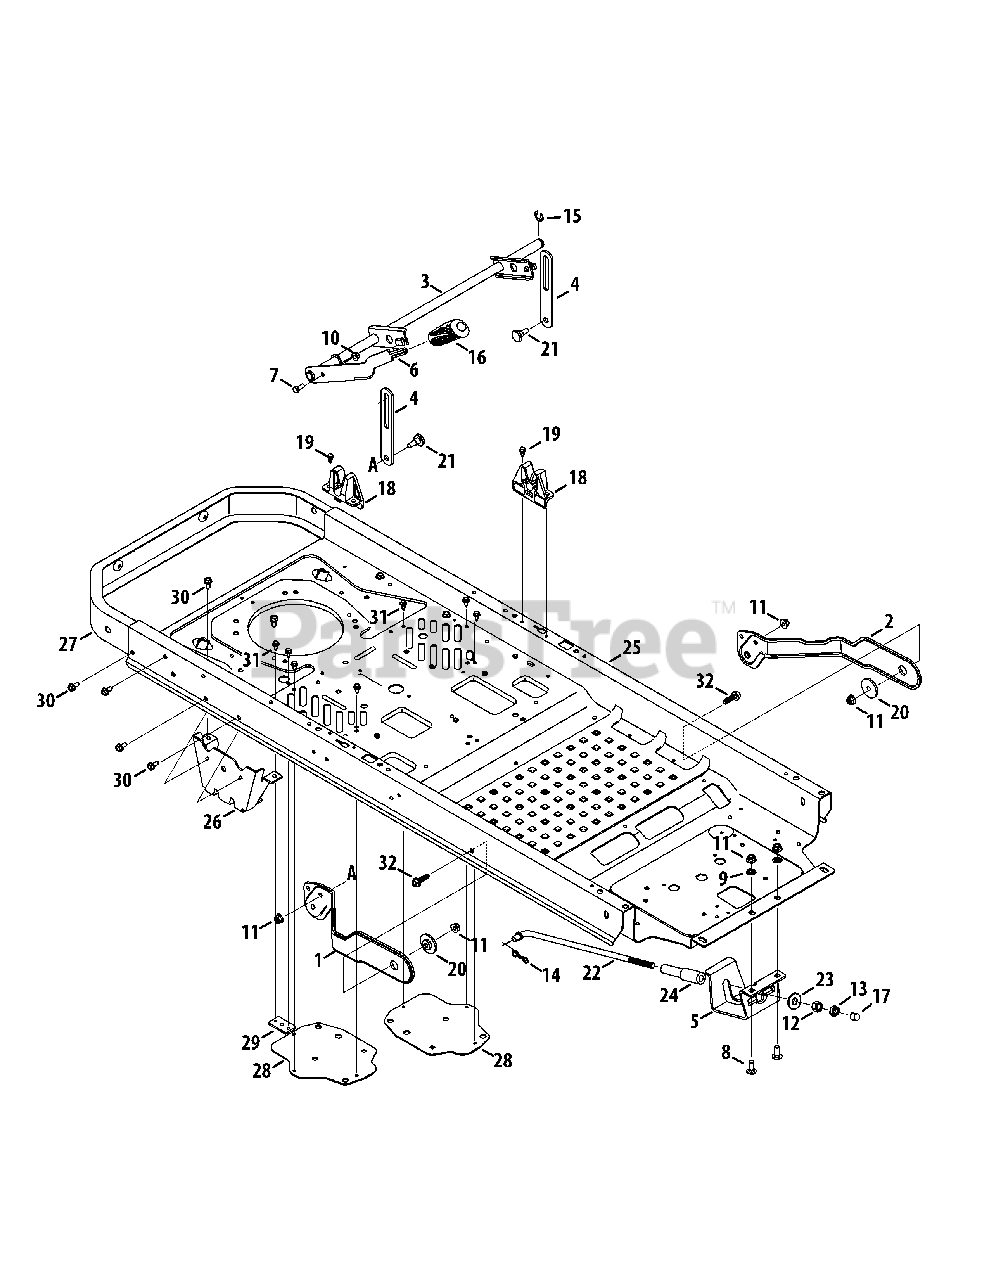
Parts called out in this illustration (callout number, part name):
1	Deck Lift Plate, RH
2	Deck Lift Plate, LH
3	Deck Lift Shift Assembly
4	Lift Link Plate
5	Rod Support Mounting Bracket
6	Deck Lift Handle
7	Hex Cap Screw, 5/16-18 x .75
8	Carriage Bolt, 3/8-16 x 1.00
9	Push Nut, 3/8
10	Flange Lock Nut, 5/16-18
11	Flange Lock Nut, 3/8-16
12	Hex Nut, 1/2-13
13	Nut, Jam, 1/2-13
14	Bow-Tie Cotter Pin
15	E-Type Ring, .750
16	Grip, .50 ID
18	Deck Lift Bracket
19	Shoulder Screw, .500 x 1/4-20
20	Shoulder Spacer, .854 x .232
21	Shoulder Screw, .500 Dia. x .434
22	Deck Lift Rod
23	Deck Lift pivot Cup
24	Nylon Sleeve, .55 ID x 4.50 LG
25	Frame Assembly
26	Axle Mounting Bracket
29	Tray Mounting Plate
30	Hex Washer Screw, 5/16-18 x .750
31	Hex Washer Screw, 1/4-20 x .625
32	Hex Washer Screw, 3/8-16 x 1.250
